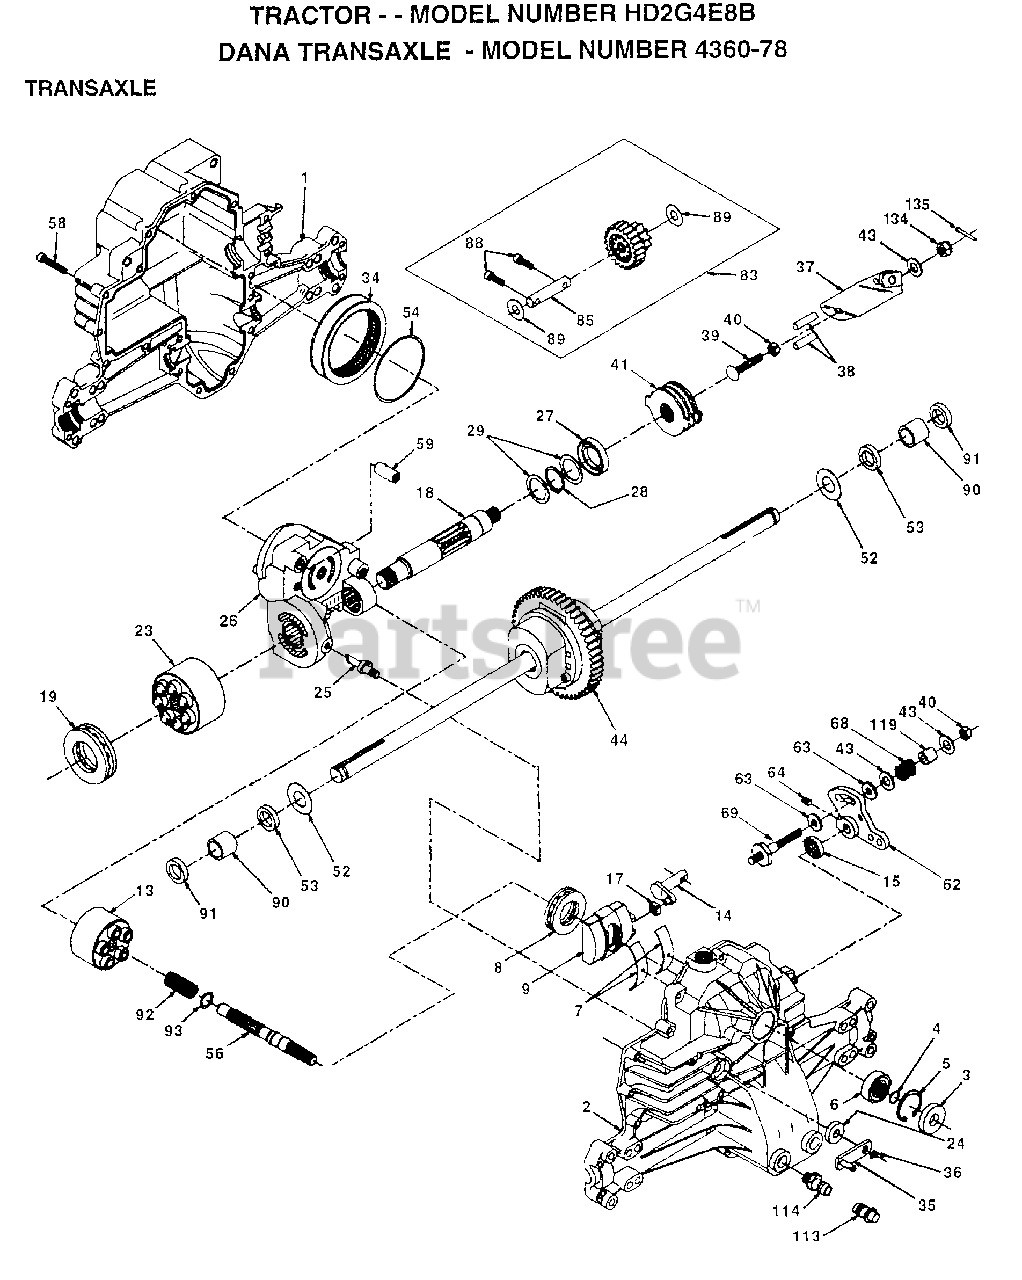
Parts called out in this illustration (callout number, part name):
1	HOUSING UPPER TRN
4	"SPRING, DETENT LT"
5	"SCREW, SET LT"
6	KIT SHIFTER ASM
7	SHIFTER BOOT
8	PUCK T
9	SEAL OIL DANA5416
11	ASM KIT SHIM 4689
13	WASHER T
14	KEY WOODRUFF-DANA
15	AS KIT INPUT SHFT
16	PINION 14T T
17	"RING,RETAINING LT"
18	"CHAIN,24 PTCH LT"
19	BEARING.FLNG.5510
20	GEAR SPUR 14 TTH
21	COLLAR CLUTCH
22	ASM KIT CLTCH KEY
23	SCREW TAP W/SEAL
24	SHAFT INTERM DANA
25	WOODRUFF KEY
26	"RING,RETAINING LT"
27	SPROCKET 18T T
28	SPACER YT
29	GEAR SPUR 37 TTH
31	GEAR 25T LT
32	GEAR SPUR 22 TT
33	SPUR GEAR 19T
34	SPACER
35	"WASHER, PLAIN LT"
36	WASHER 025
37	SPACER
38	ASSM GEAR COMB
39	SHAFT IDLER
40	SPACER T
41	SPROCKET 9T LT
43	ASM KIT SHIM
44	SHAFT T
45	GEAR SPUR 12 TTH
47	"GEAR, SPUR 25T LT"
48	GEAR 28T T
49	"GEAR, SPUR 31T LT"
51	WASHER 060
52	NEOPRENE WASHER
53	WASHER 031
55	GEAR 15T T
56	"RING,RETAINING LT"
58	SHAFT T
59	GEAR 1ST T
61	HOUSING LOWER TNS
62	PUCK T
63	BRAKE DISC. T
64	SPACER LT
66	PIN T
69	WASHER LT
71	NUT.LOCK.5/16-24
72	"SCREW, TAPPING LT"
